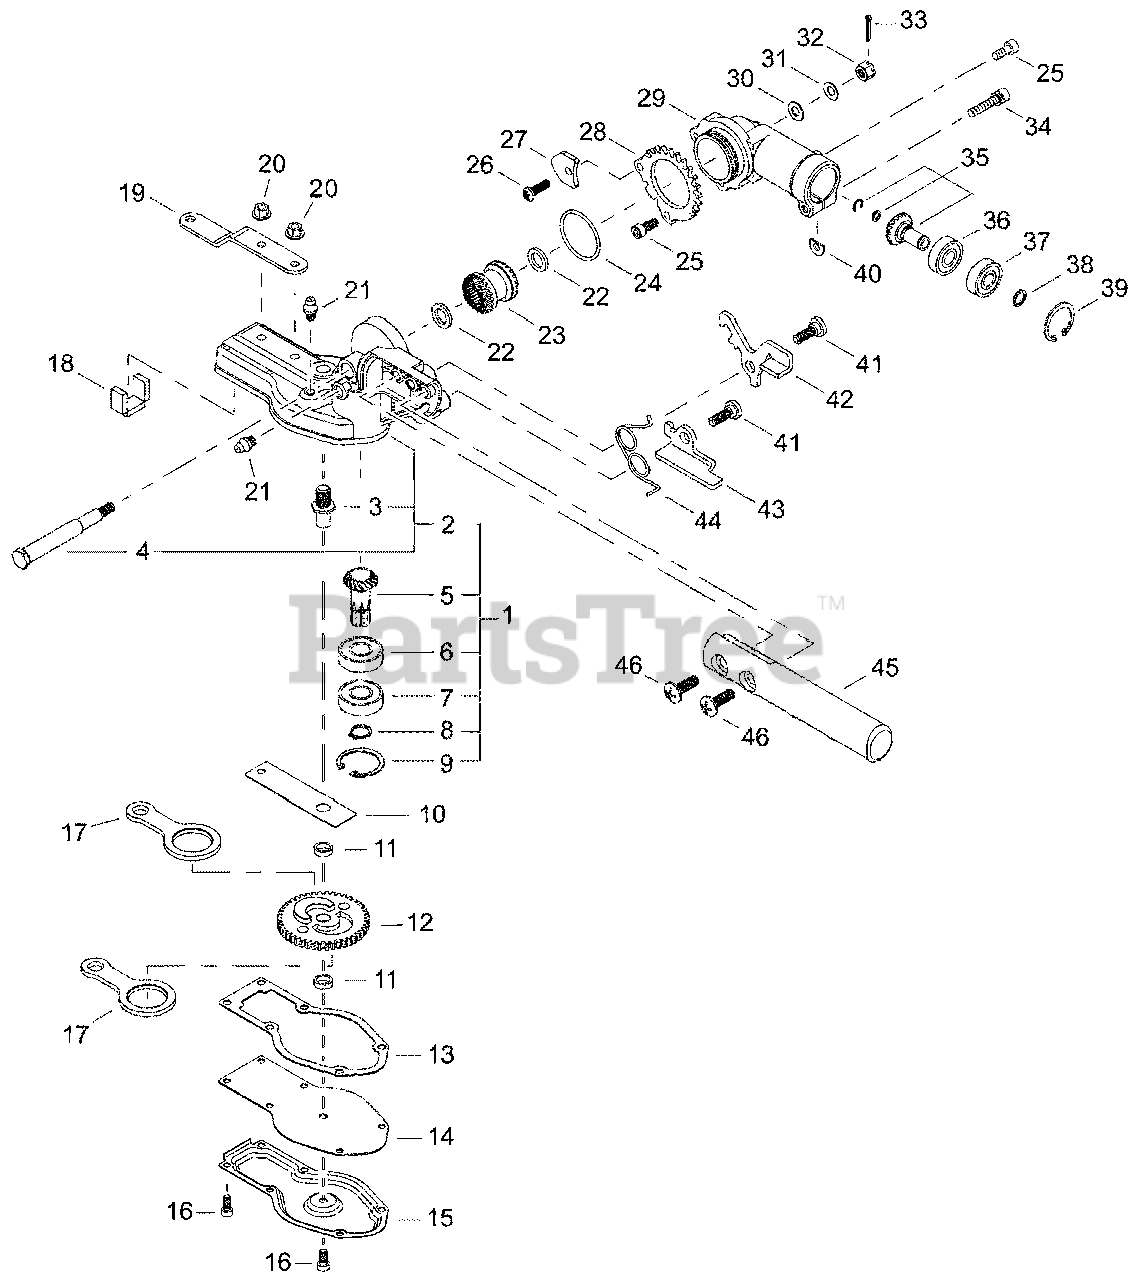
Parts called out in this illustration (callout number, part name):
1	GEAR CASE HOUSING KIT
2	GEAR CASE HOUSING ASSY
3	MAINSHAFT
4	SHAFT
5	SHAFT, PINION
6	BEARING, BALL 6001
7	BEARING, BALL 6001ZZ
8	RING, SNAP Ø12
9	RING, SNAP Ø28
10	PLATE, GUIDE
11	SPACER Ø11ר8×3.4
12	GEAR, CAM
13	GASKET, GEAR CASE
14	SPACER
15	COVER, GEAR CASE
16	BOLT 4×10
17	CONROD
18	PACKING, FELT
19	BRACKET, CUTTER
20	NUT, FLANGE M5
21	FITTING, GREASE
22	COLLAR Ø16ר10×L= 2
23	GEAR, BEVEL
24	O-RING
25	BOLT 5×12
26	SCREW M5×16
27	PLATE, STOPPER
28	RING, LOCKING
29	HOUSING, UPPER GEAR CASE
30	WASHER 6.5×13×1
31	WASHER, CONE M6
32	NUT M6
33	PIN, COTTER Ø1.6×15
34	BOLT M5×25
35	PINION SET, BEVEL
36	BEARING, BALL 609
37	BEARING, BALL 609ZZ
38	RING, SNAP
39	RING, SNAP Ø24
40	D-WASHER
41	BOLT M6
42	LEVER, LOCK
43	RELEASE, LOCK
44	SPRING, TORSION
45	LEVER, ADJUSTMENT
46	SCREW, TRUSS M6×20
